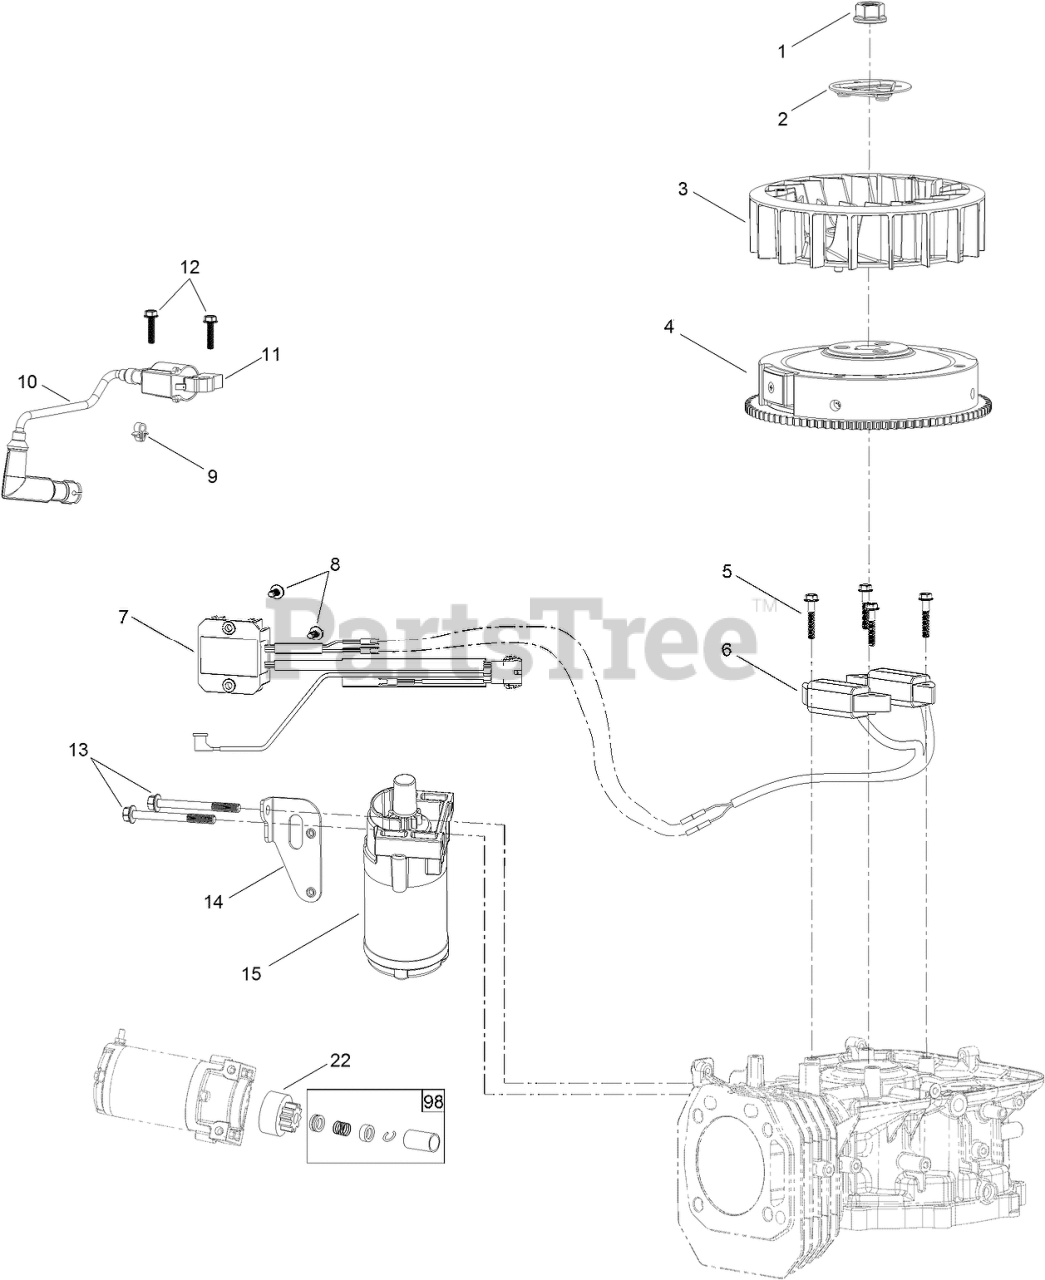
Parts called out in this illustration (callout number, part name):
1	NUT-FLANGE
2	PULLEY-STARTER
3	FAN-COOLING
4	FLYWHEEL
5	SCREW-HHF
6	ALTERNATOR
7	VOLTAGE REGULATOR
8	SCREW-HHF
9	CLAMP-WIRE
10	BOOT-PLUG, SPARK
11	IGNITION COIL ASM
12	SCREW-HHF
13	SCREW-HHF
14	BRACKET-STARTER
15	MOTOR-STARTER
22	PINION-STARTER
98	STARTER REPAIR KIT
